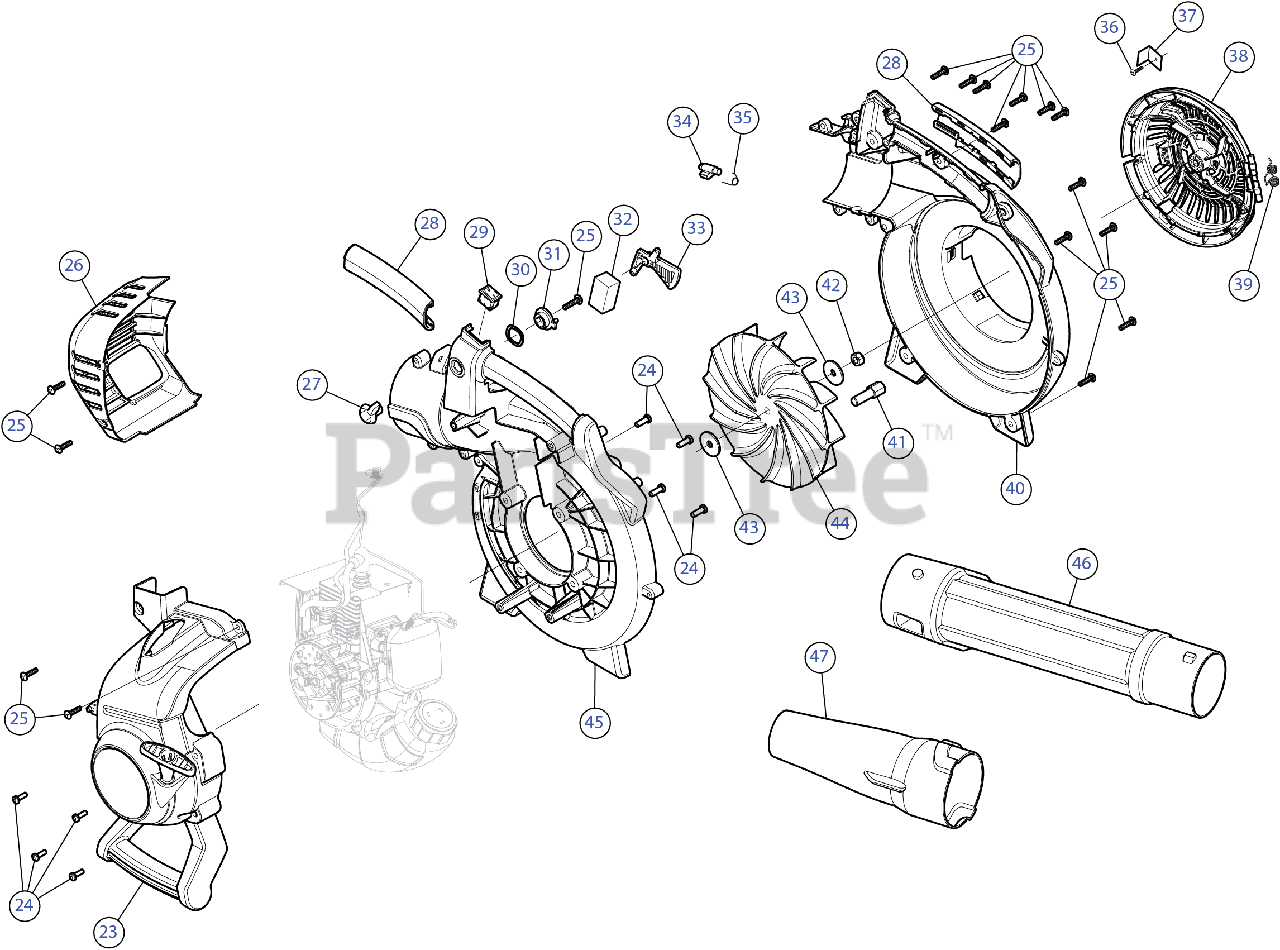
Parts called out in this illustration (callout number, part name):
23	STARTER HOUSING ASSEMBLY
24	SCREW:10-32X.562:#8P
25	SCREW 8-16 x 3/4
26	MUFFLER COVER
27	TRIGGER LOCK OTR
28	ANDLE GRIP ASSEMBLY
29	SW, MOMENTARY ON/O
30	WASHER WAVEY
31	TRIGGER LOCK INR
32	AIR FILTER
33	THROTTLE TRIGGER
34	LATCH TUBE
35	SPRING LATCH
36	SCREW-10-9 x .50
37	DOOR LOCK SC
38	INTAKE COVER
39	SPRING
40	IMPELLER HOUSING OTR
41	ADAPTER STARTER
42	HEX NUT CENTER
43	WASHER FLAT
44	IMPELLER
45	IMPELLER HOUSING INR
46	UPPER TUBE
47	NOZZLE BKPK CUB
